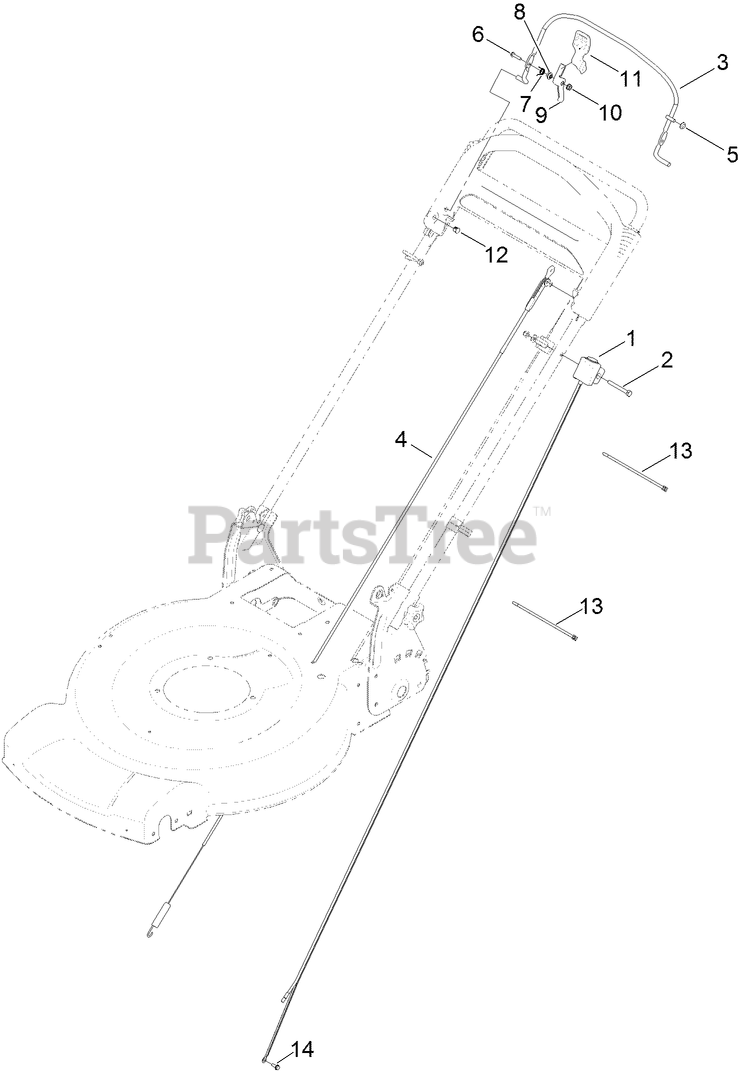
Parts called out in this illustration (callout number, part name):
1	SWITCH HOUSING ASM
2	SCREW-HH
3	BAIL-BRAKE
4	CABLE-BRAKE
5	NUT-SPEED
6	SCREW-HWH
7	SPRING-TORSION
8	SPACER
9	LEVER
10	NUT-LOCK, FLANGE
12	PLUG-DOME
13	TIE-CABLE
14	SCREW-TAPTITE
